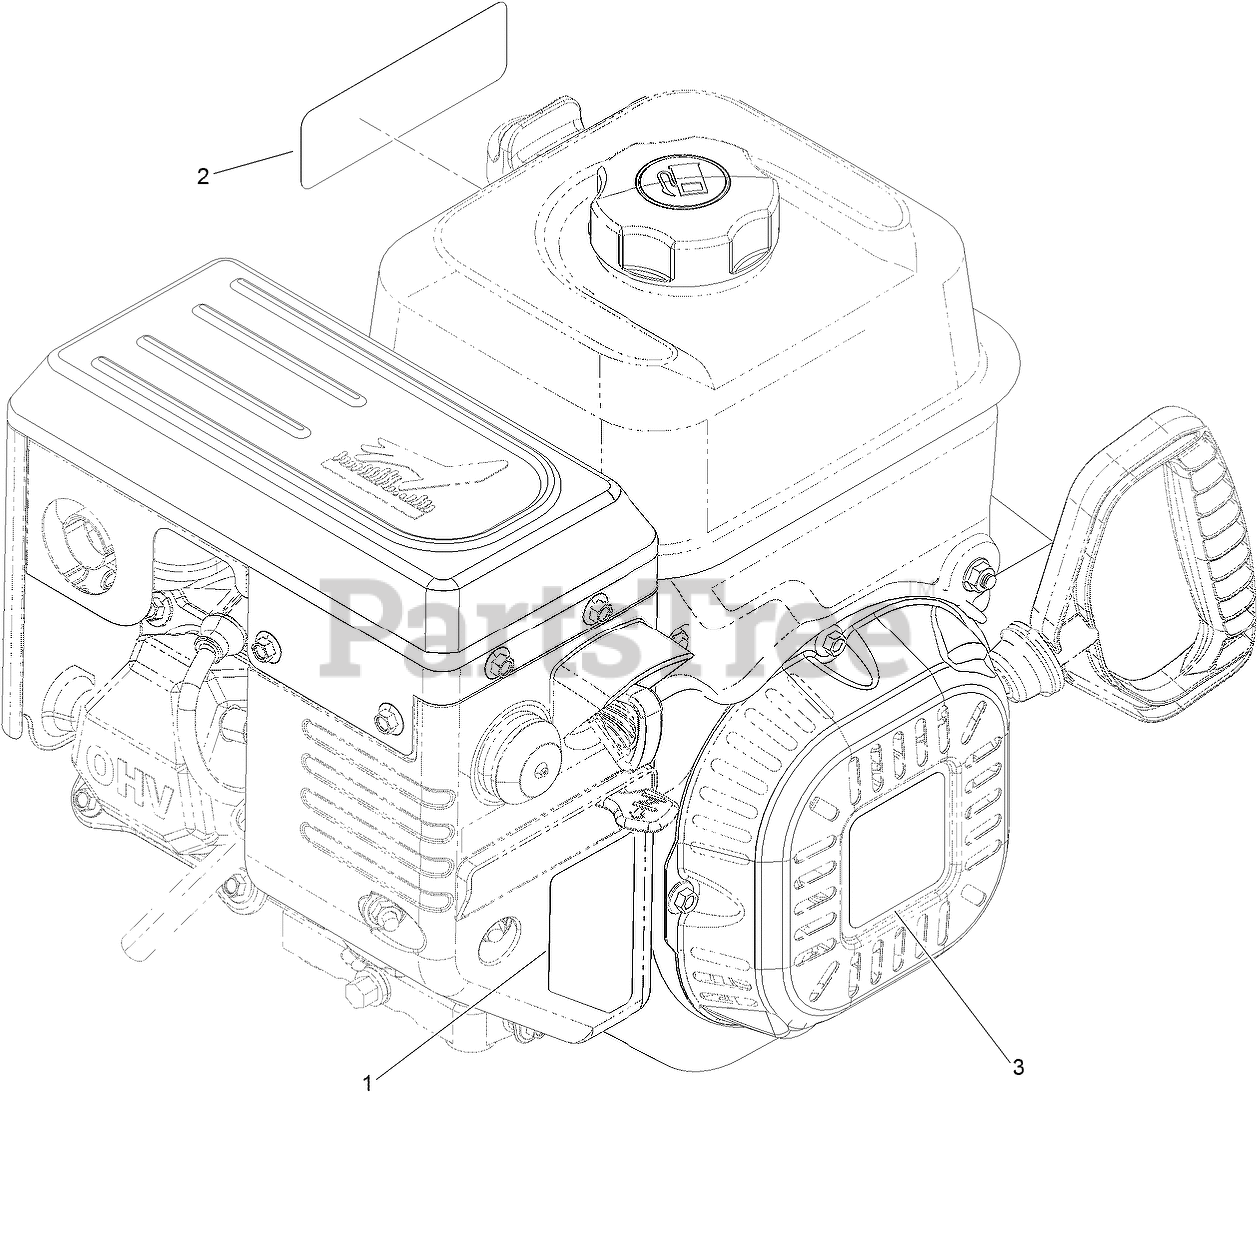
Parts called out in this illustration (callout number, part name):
1	DECAL-CONTROL, ENGINE
2	DECAL-ENGINE, SERIES G210
3	DECAL-RECOIL, G210
